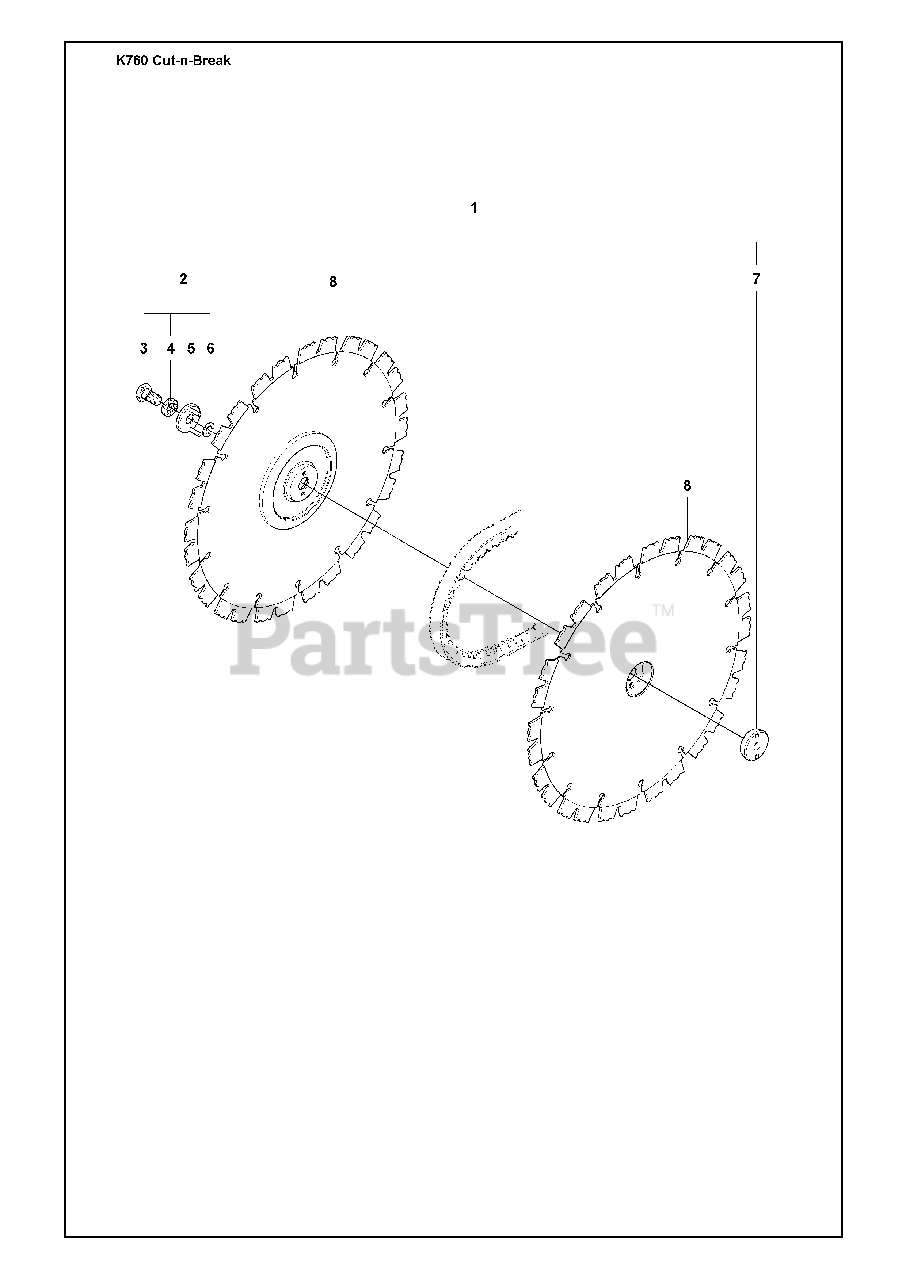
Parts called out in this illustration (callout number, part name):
1	Screw Assy
7	Center Nut
8	Cutting Blade
